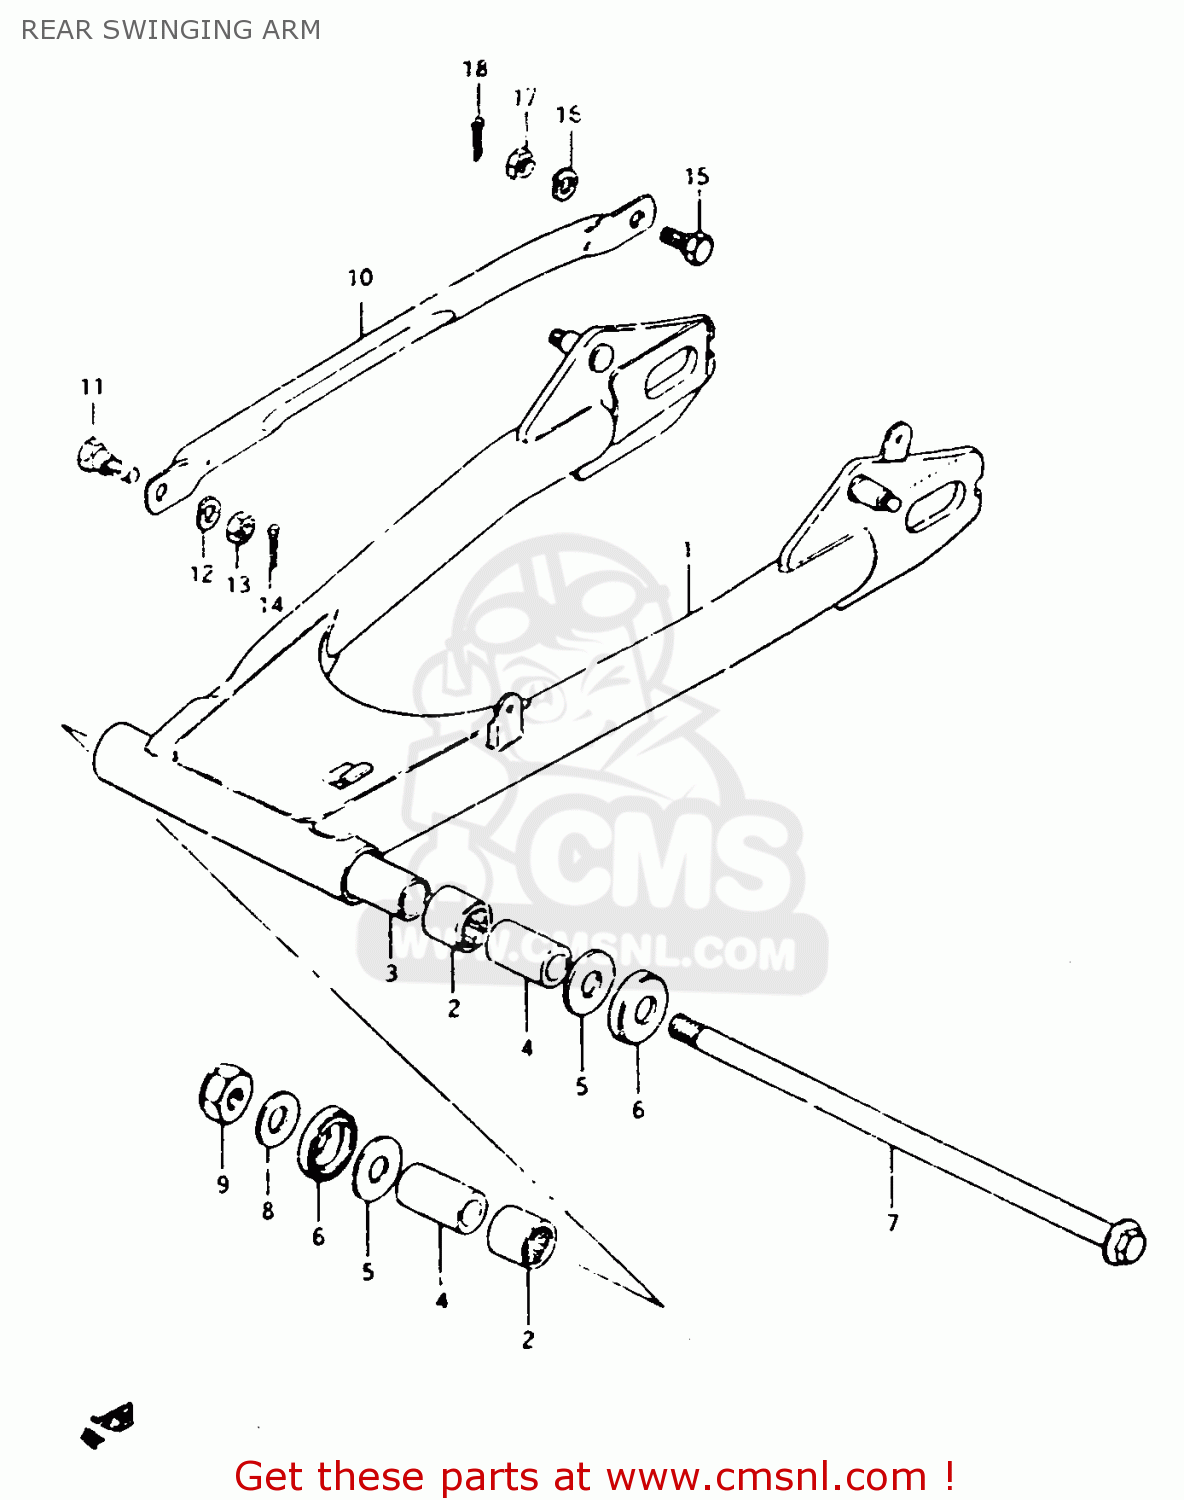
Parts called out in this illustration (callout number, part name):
1	ARM,REAR SWING
2	BEARING(22X29X30)
3	SPACER,SWINGINGARM CTR
4	SPACER,RR SWGARM PIVOT
5	WASHER(14.2X34X1)
6	CVR,RR SWGARM DUST SEAL(OD:40)
7	SHAFT,REAR SWING ARM
8	WASHER
9	NUT 14MM
10	LINK,REAR TORQUE
11	BOLT(10X24.5)
12	LOCK WASHER
13	NUT
14	PIN 20X20
15	BOLT(10X31)
16	LOCK WASHER
17	NUT
18	PIN 20X20
